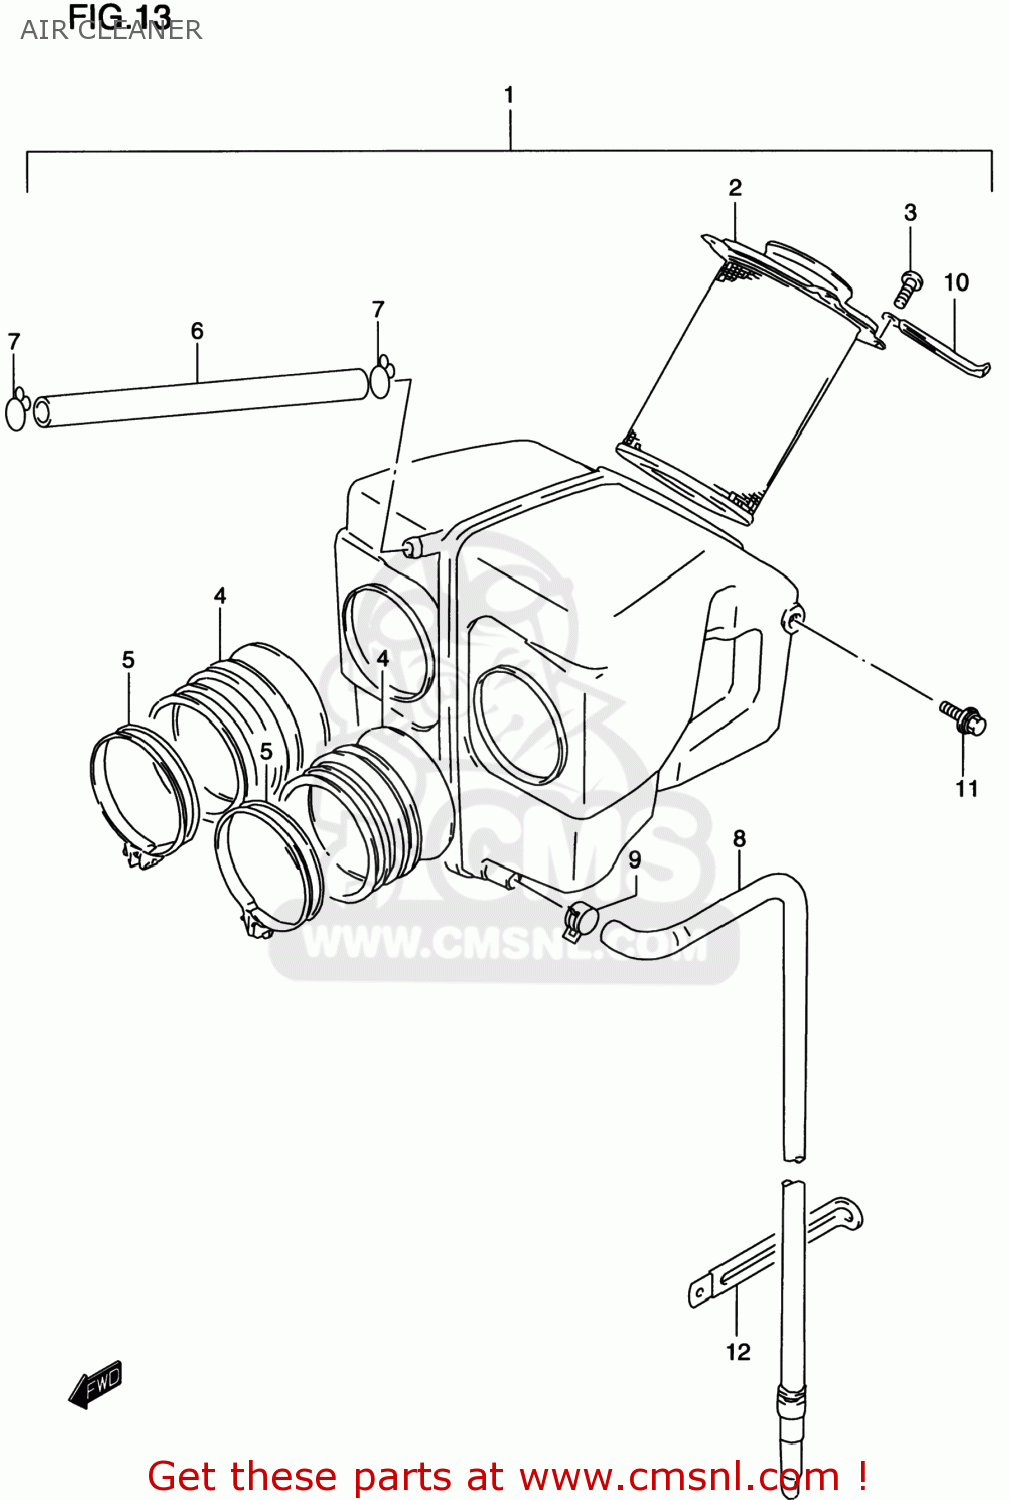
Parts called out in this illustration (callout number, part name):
1	CLEANER ASSEMBLY,AIR
2	FILTER ASSY
3	SCREW
4	TUBE,OUTLET
5	CLAMP
6	HOSE(11X15X600)
7	CLIP
8	TUBE,DRAIN
9	CLIP
10	CLAMP
11	SCREW
12	CLAMP(L:80 T:1.0)
